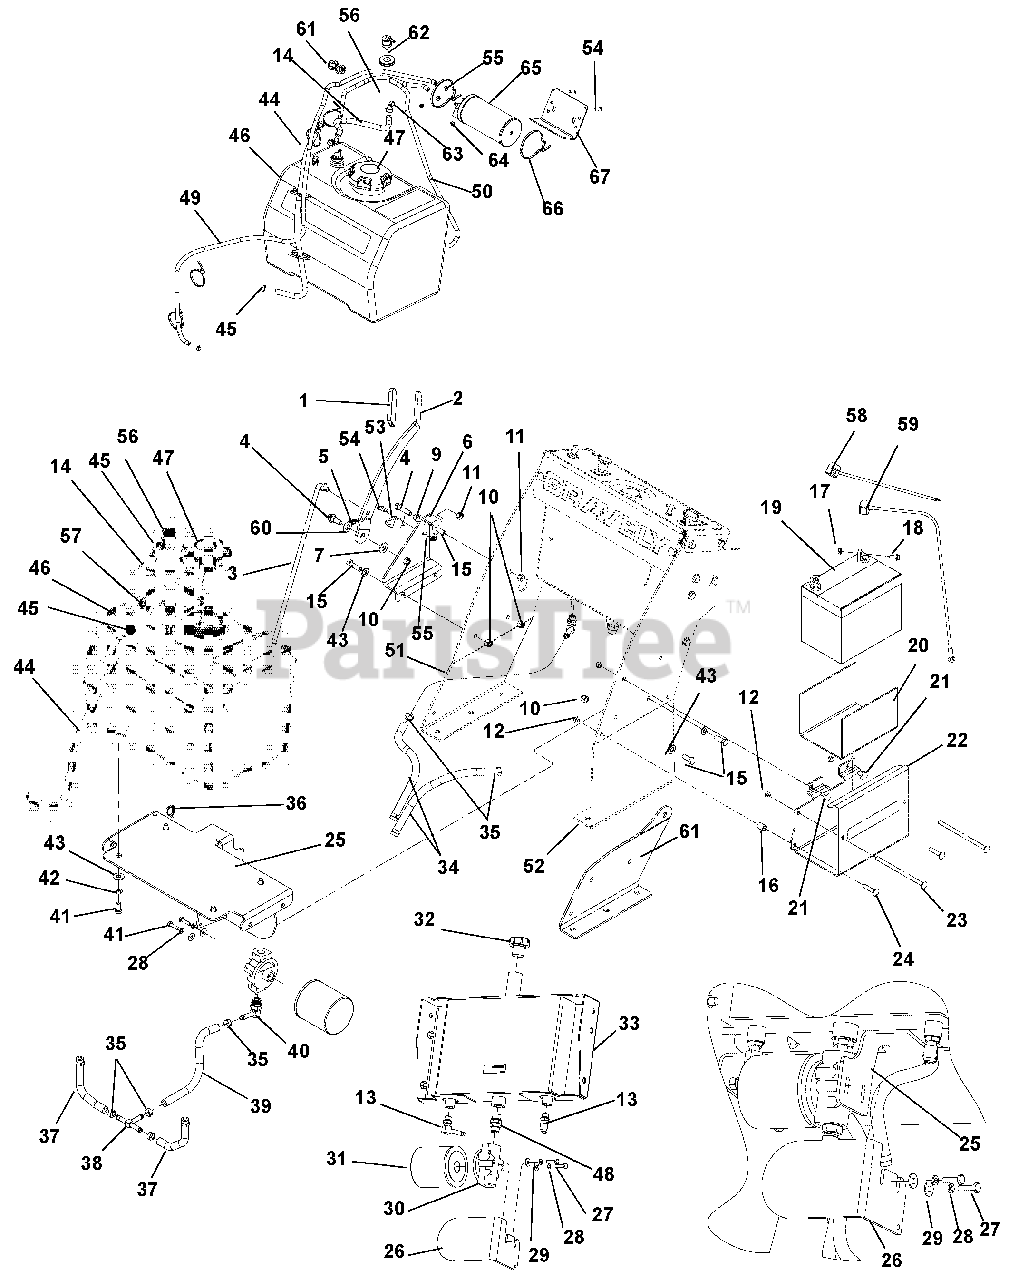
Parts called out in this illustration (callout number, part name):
1	GRIP
2	LEVER, HAND BRAKE
3	ROD, DRIVE CONTROL FW
4	BLT-HEX .38-16X1.50 GR5 YWZC
5	RING, RUE .375 X .054 X 1.254
6	LOCATOR, BRAKE ARM WD
7	BUSHING, BRAKE LEVER STAND OFF
8	BOLT, .38-16 X 1.00 HEX 5 Y
9	LOCKNUT, 3/8-16 WHIZ Y
10	LOCKNUT, 3/8-16 NYLOC Y
11	LOCKNUT, 3/8-16 CENTER Y
12	LOCKNUT, 5/16-18 NYLOC Y
13	FITTING, 90 9/16 MOR X 3/8 HOSE
14	HOSE, FUEL HYDRO TANK - ROV
15	BOLT, .38-16 X 1.00 HEX 5 Y
16	BUSHING, .364X.540X.700 Y
17	LOCKNUT, 1/4-20 WHIZ Y
18	BOLT, .25-20 X .75 WSH Y
19	BATTERY, 12V-U1-CCA270MIN
20	STRIP, BATTERY INSULATOR
21	BOLT, RDHDSQNK .31-18 X .75 G5Y
22	TRAY, BATTERY ELEC
23	BOLT, 5/16-18 X 6.00 CRG 2 Y
24	BOLT, RDHDSQNK .31-18 X 1.50 G5YZ
25	BRKT, GRAVELY FUEL TANK
26	GUARD, HYDRO FILTER FLWLK
27	BOLT, .25-20 X 1.00 HEX 5 Y
28	WASHER, LOCKING .25 x .062 REGULAR
29	WASHER, FLAT-STL.312 x .734 x .065
30	HEAD, OIL FILTER
31	FILTER, OIL
32	CAP, OIL FILL BREATHER
33	WLDT, TANK
34	HOSE, HYD .375 X 11.5
35	CLAMP, HOSE - 1/2" PINCH
36	CABLE TIE, .15 X 8.50
37	HOSE, HYD 3/8 X 6.00
38	FTG, TUN 3/8 HOSE
39	HOSE, HYD. .375 X 12
40	FTG, 90 BRB-OR 4601-06-08
41	BOLT, .38-16 X .750 HEX 5 Y
42	WASHER, .375 MED SPRG LOCK Y
43	WASHER, FLAT-STEEL .406 X .812 X .065
44	HOSE, FUEL 1/4 X 18.00
45	CLAMP, HOSE - 1/2" SPRING
46	ASSY, FUEL TANK
47	CAP, FUEL
48	STRAIGHT UNION SAE 8
49	HOSE, ACTIVE FUEL
50	HOSE, FUEL HYDRO ROV - CC
51	WLDMT, RH UPRIGHT TOWER PG WD
52	WMT, LH UPRIGHT TOWER-22" WD RD
53	SWITCH- DOUBLE POLE N.O./N.O.
54	SCREW, 10-24 X .75 HWH
55	NUT, LOCK 10-24 NYLOC
55	NUT, 10-24 KEPS
56	VALVE, COMBINATION
57	VALVE, REMOTE ROLL OVER
58	CABLE, BATTERY GROUND 25"
59	CABLE, BATTERY - 25" POSITIVE
60	WASHER-FL-STL .438 X 1.00 X .083
61	BUSH, PANEL SNAP .687X.875X.56
62	GROMMET, REMOTE ROV
63	CLAMP, DBL PINCH 5/16" - 7/16"
64	CLAMP - HOSE, SPRING .188
65	400 CC CARBON CANISTER 3/16 PT
66	CABLE TIE, .19 X 14.4
67	BRKT, CARB CANISTER MTG
